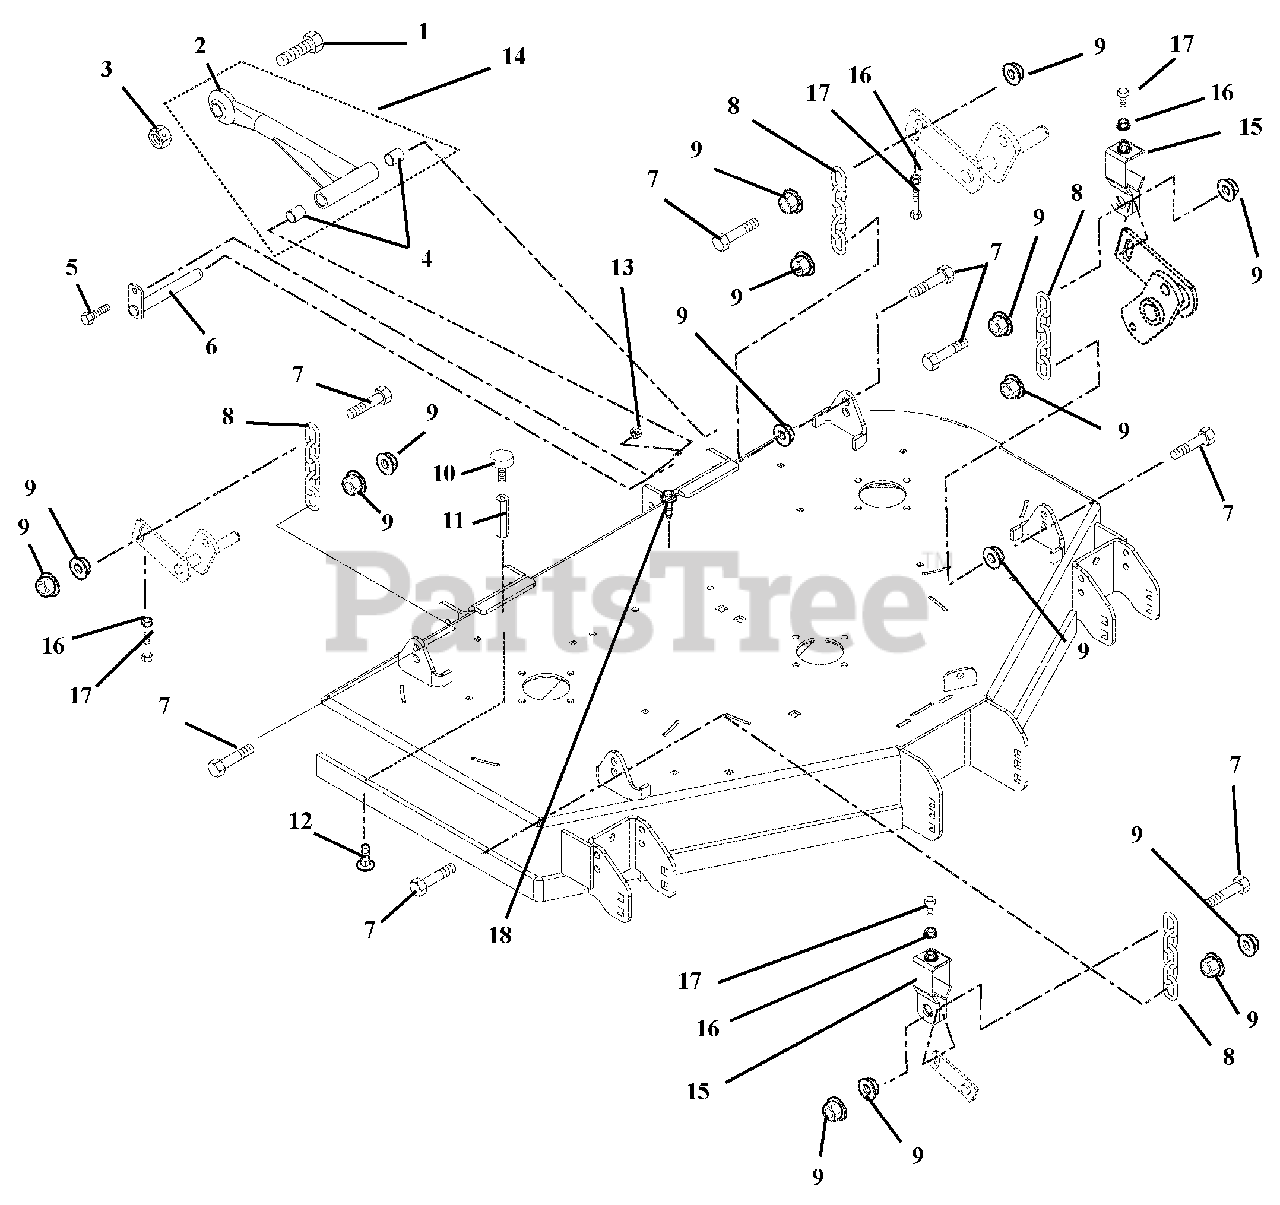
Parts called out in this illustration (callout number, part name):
1	Bolt, Hex .875-9 x 2.75 Grade 5
2	Mower Mounting Arm Weldment
3	Nut, Locking-Center .875-9
4	Bearing, .75 x .875 x 1.00
5	Bolt, Hex .38-16 x .75 Grade 5
6	Weldment, Mower Mounting Pin
7	Bolt, Hex M12-1.75 x 50 Grade 5
8	Chain, Link
9	Nut, Spin Lock-Flange M12-1.75
10	Bumper, Rubber
11	Nut, Coupling .31-18 x 3.00
12	Bolt, Round Head Square Neck .31-18 x .75 Loctite with Epoxy Patch
13	Nut, .38-16 Nyloc Flange
14	Assembly, Mower Mounting Arm (Includes item # 2 and item # 4)
15	Bracket, Deck Leveling
16	Nut-Jam .312-18
17	Bolt, Hex .31-18 x 2.00 Full Thread
18	Screw, Tapping .38-16 x .50 Hex Washer Head Thread
